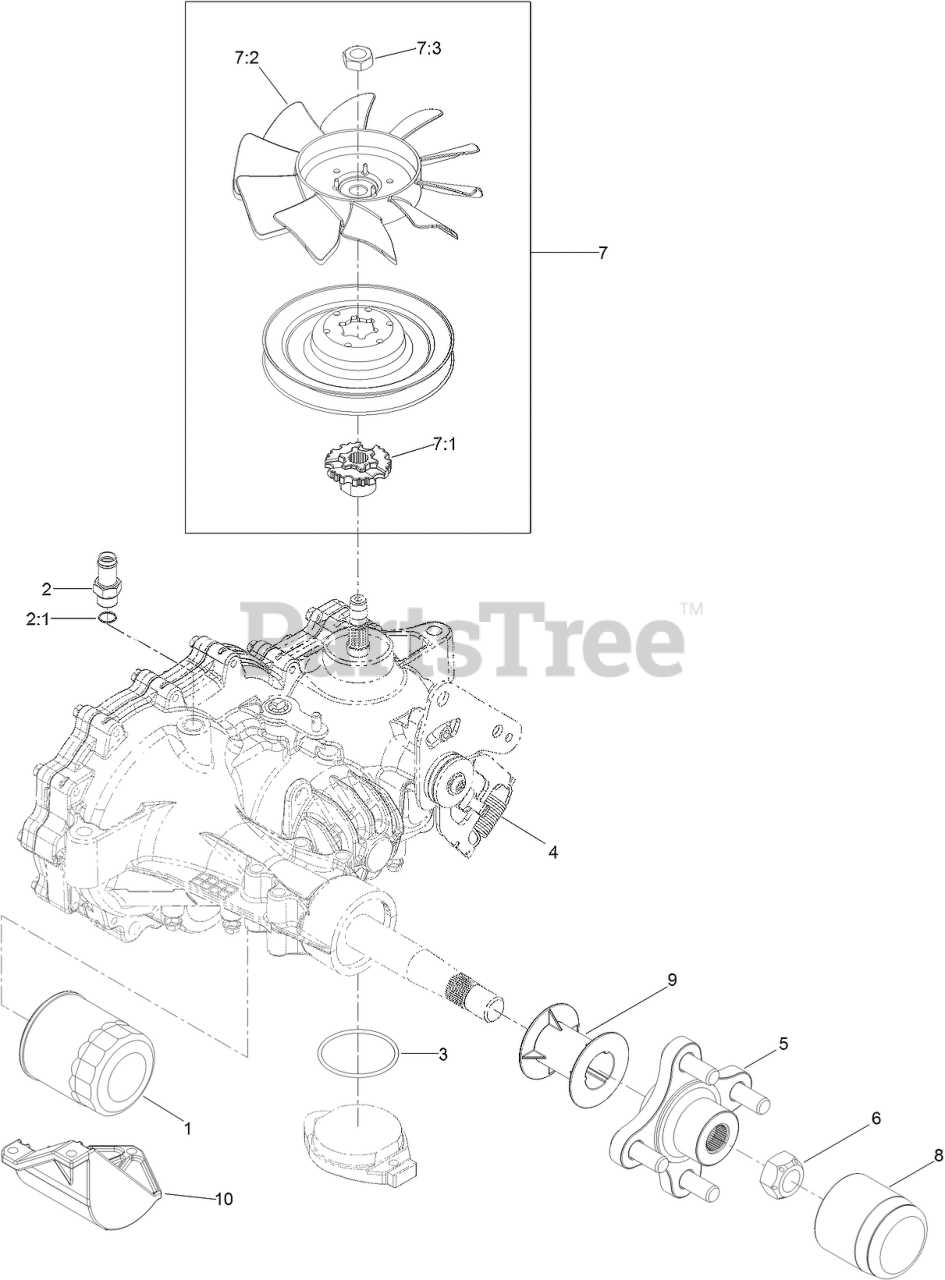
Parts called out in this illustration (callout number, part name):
1	ELEMENT-OIL FILTER, HYD
2	ADAPTER-STRAIGHT
2:1	O-RING
3	O RING-SEAL
4	SPRING-EXTENSION
5	HUB-OFFSET
6	NUT-HUB
7	FAN AND PULLEY KIT
7:1	HUB-FAN
8	CAP-AXLE, LONG
9	TUBE-AXLE
10	GUARD-FILTER, RH
